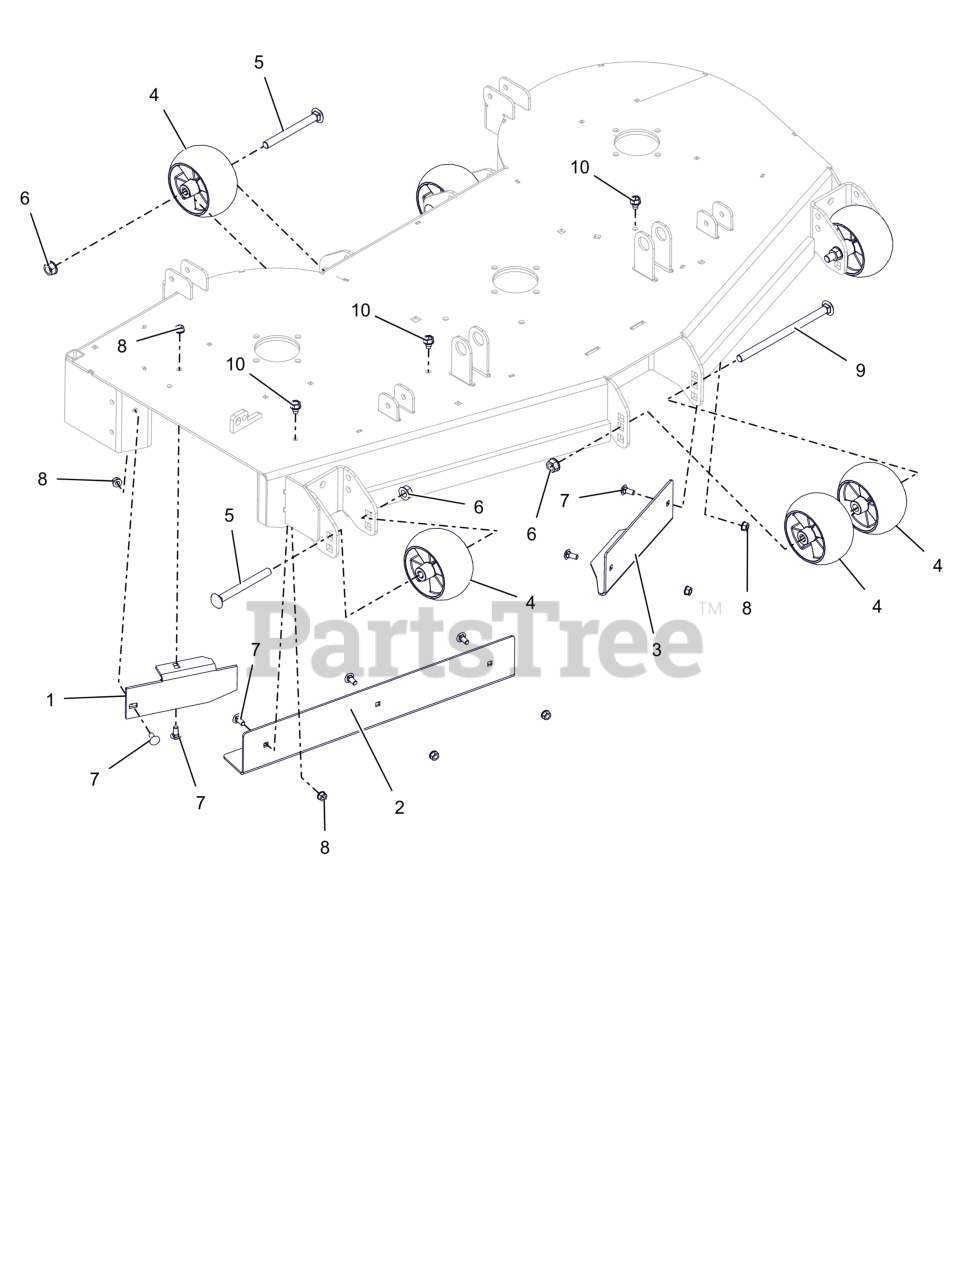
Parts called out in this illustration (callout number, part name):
1	52" DISCHARGE BAFFLE - RED
2	BAFFLE, 52" RH VACUUM (RED)
3	BAFFLE, 52" LH VACUUM (RED)
4	WHEEL, ANTI SCALP - 5X3 CTR W/RIBS
5	BLT, RHSN .50-13X5.00 G5 ZCC
6	NUT-LK-CTR-FLG .500-13 GG ZCC
7	BLT,RHSN .31-18X.75 G5 ZCC
8	NUT,LK-CTR-FLG .31-18 GF ZCC
9	BTL,RHSN .500-13 X 8.5S G5 ZCC
10	SCR,TAP .375-16X.50 HWH TR ZCC
